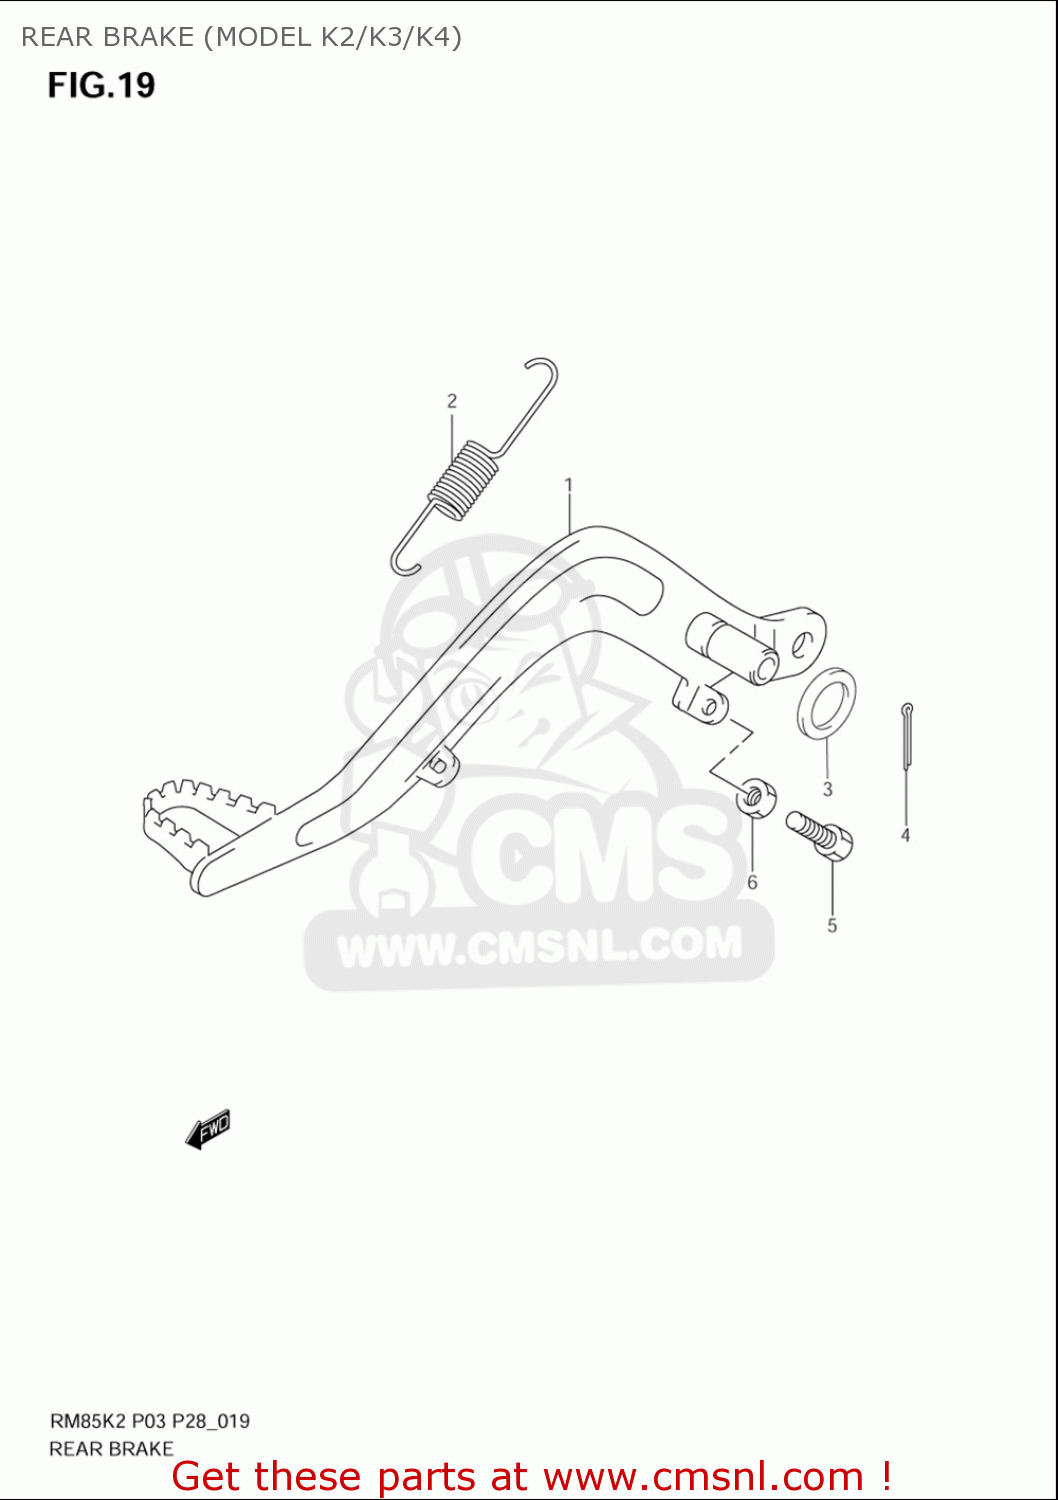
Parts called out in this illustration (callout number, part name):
1	PEDAL,BRAKE
2	SPRING
3	WASHER(15.5X24X2.3)
4	PIN, COTTER
5	SCREW(6X23)
6	NUT
